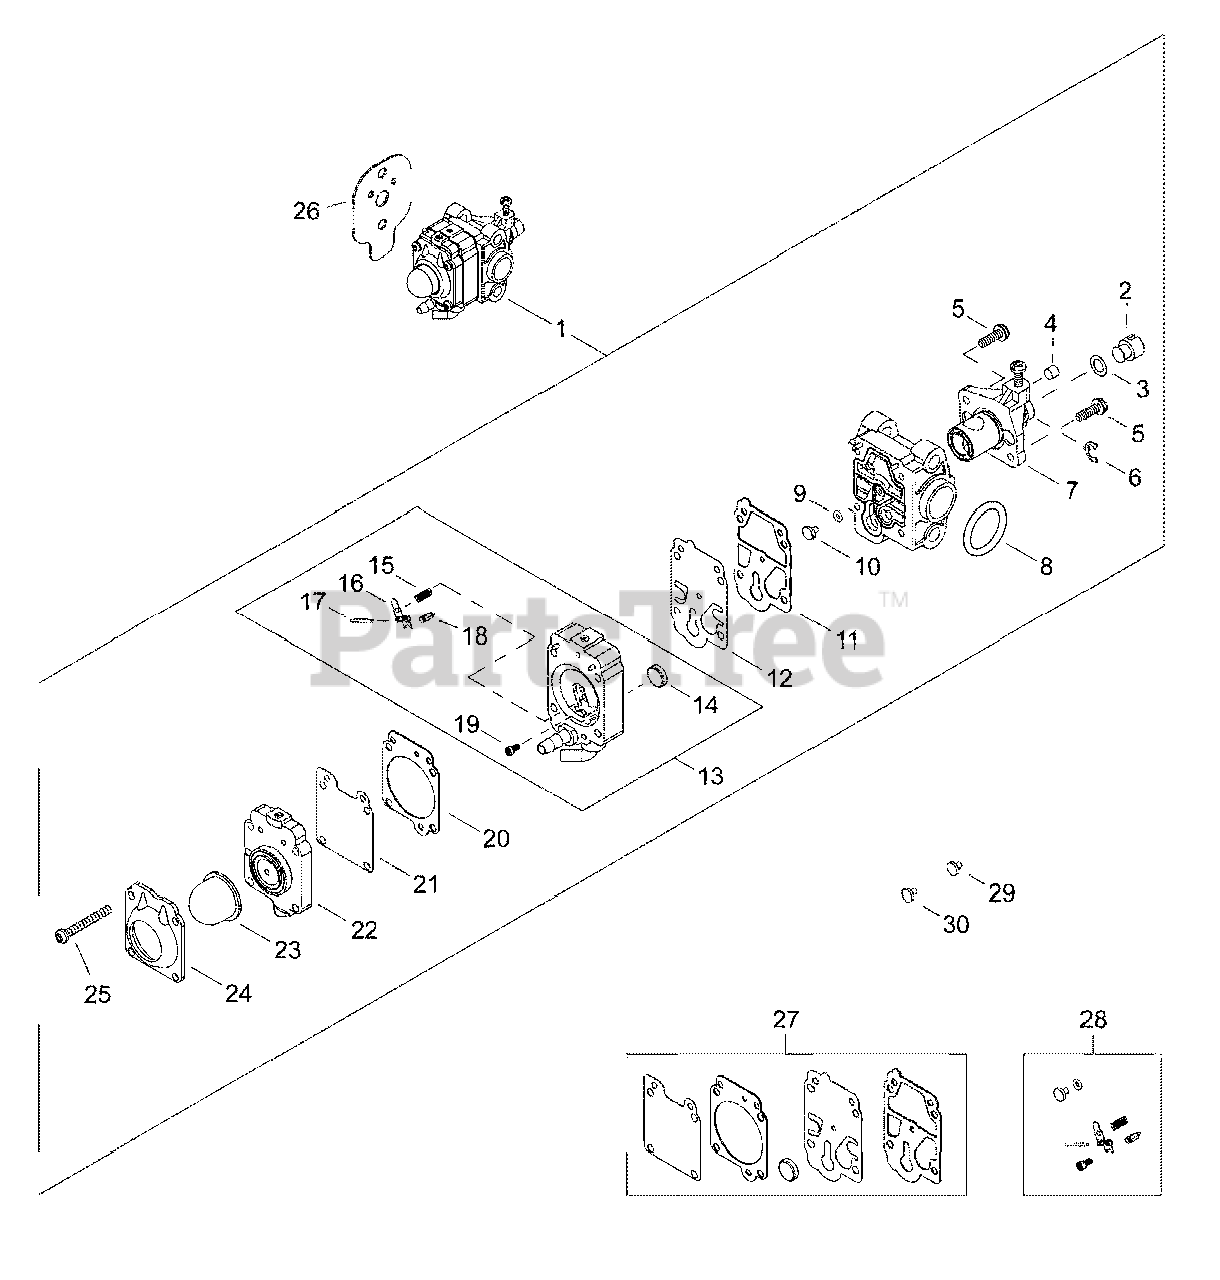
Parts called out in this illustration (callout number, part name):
1	CARBURETOR
2	SWIVEL
3	WASHER
4	PLUG
5	SCREW, THROTTLE COLLAR
6	E-RING
7	VALVE ASSY, THROTTLE
8	O-RING 15
9	O-RING
10	JET, MAIN
11	GASKET, PUMP
12	DIAPHRAGM, PUMP
13	BODY ASSY, PUMP
14	SCREEN, FUEL INLET
15	SPRING, METERING LEVER
16	LEVER, METERING
17	PIN, METERING LEVER
18	VALVE, INLET NEEDLE
19	SCREW
20	GASKET, METERING DIAPHRAGM
21	DIAPHRAGM, METERING
22	BODY ASSY, PURGE
23	BULB, PURGE
24	RETAINER, PURGE BULB
25	SCREW
26	GASKET, INTAKE
27	GASKET / DIAPHRAGM KIT
28	VALVE KIT, INLET NEEDLE
29	JET, MAIN
30	JET, MAIN
